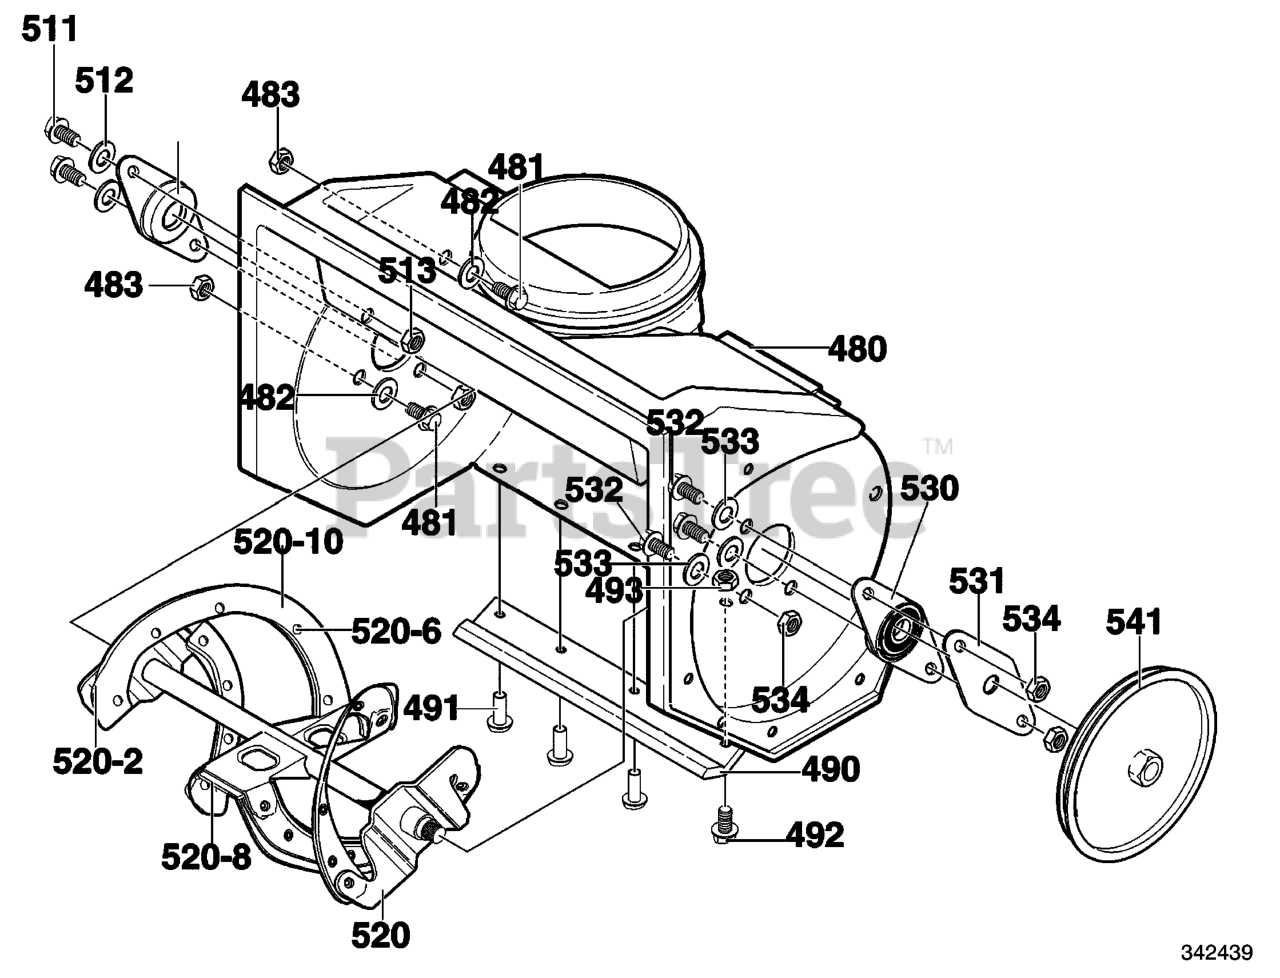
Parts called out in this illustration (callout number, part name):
480	HOUSING, ASSY
481	SCREW, 1/4-20X.75
482	WASHER, FLAT .281X.63X.065
483	NUT, 1/4-20
490	BLADE, SCRAPER
491	RIVET, OVSET
492	SCREW, 1/4-20X.75
493	NUT, 1/4-20
510	BRNG,FL
511	SCREW, 1/4-20X1.00
512	WASHER, FLAT .281X.63X.065
513	NUT, 1/4-20
520	AUGER, ASSY
520-2	BLADE, AUGER
520-6	RIVET
520-8	BLADE, CENTER
520-10	AUGER & BLADE SUPPORT
530	BEARING & PLATE ASSY.
531	PLATE, RETAINER
532	SCREW, 1/4-20X.63
533	WASHER, FLAT .281X.63X.065
534	NUT, 1/4-20
